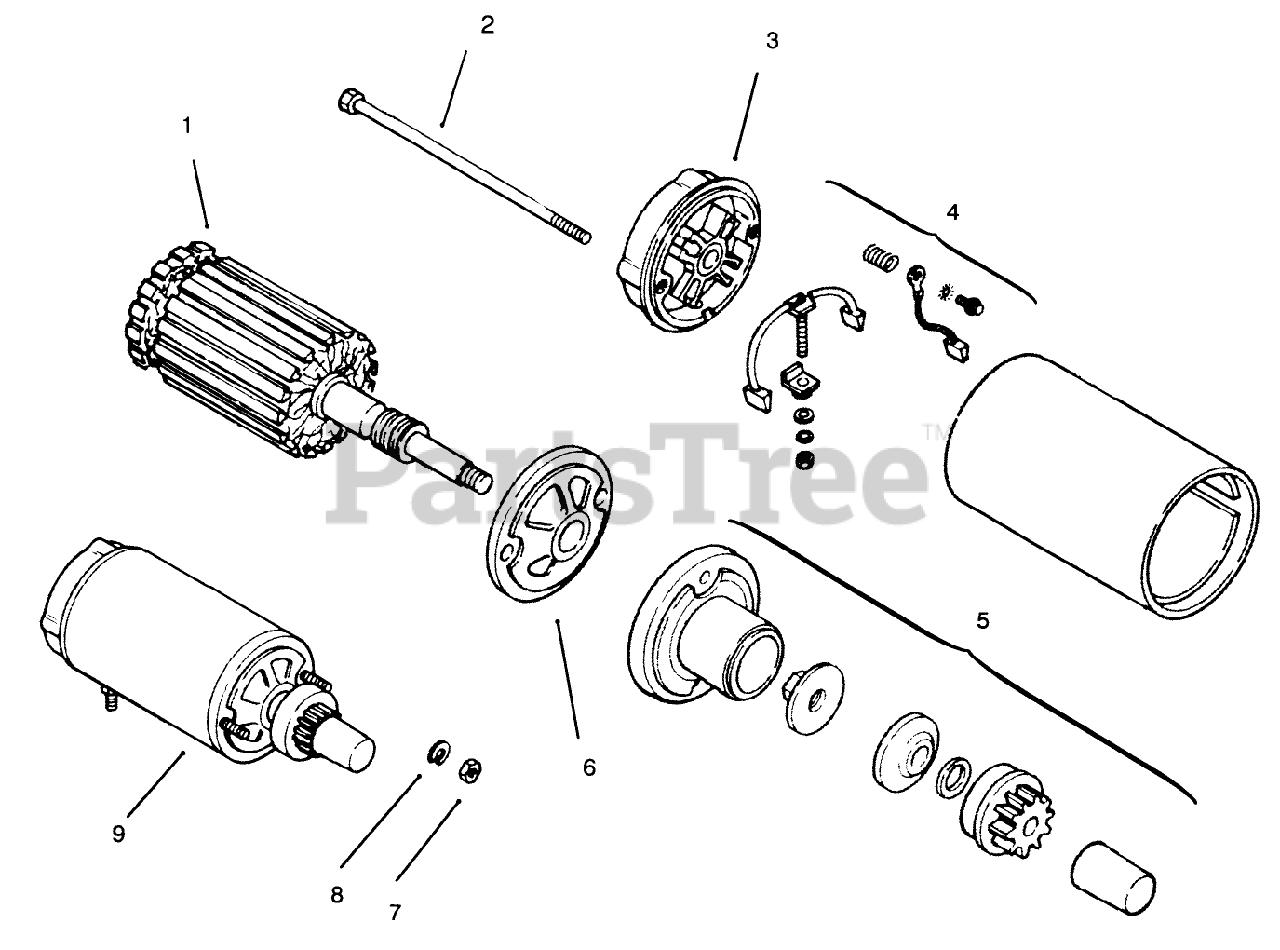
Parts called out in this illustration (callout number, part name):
1	Armature
2	Bolt
3	Cap-Commutator End
4	Kit-Brush
5	Kit-Drive
6	Cap-Drive End
7	Nut
8	Washer
9	Starter Assembly (Incl. Ref.#1-8)
